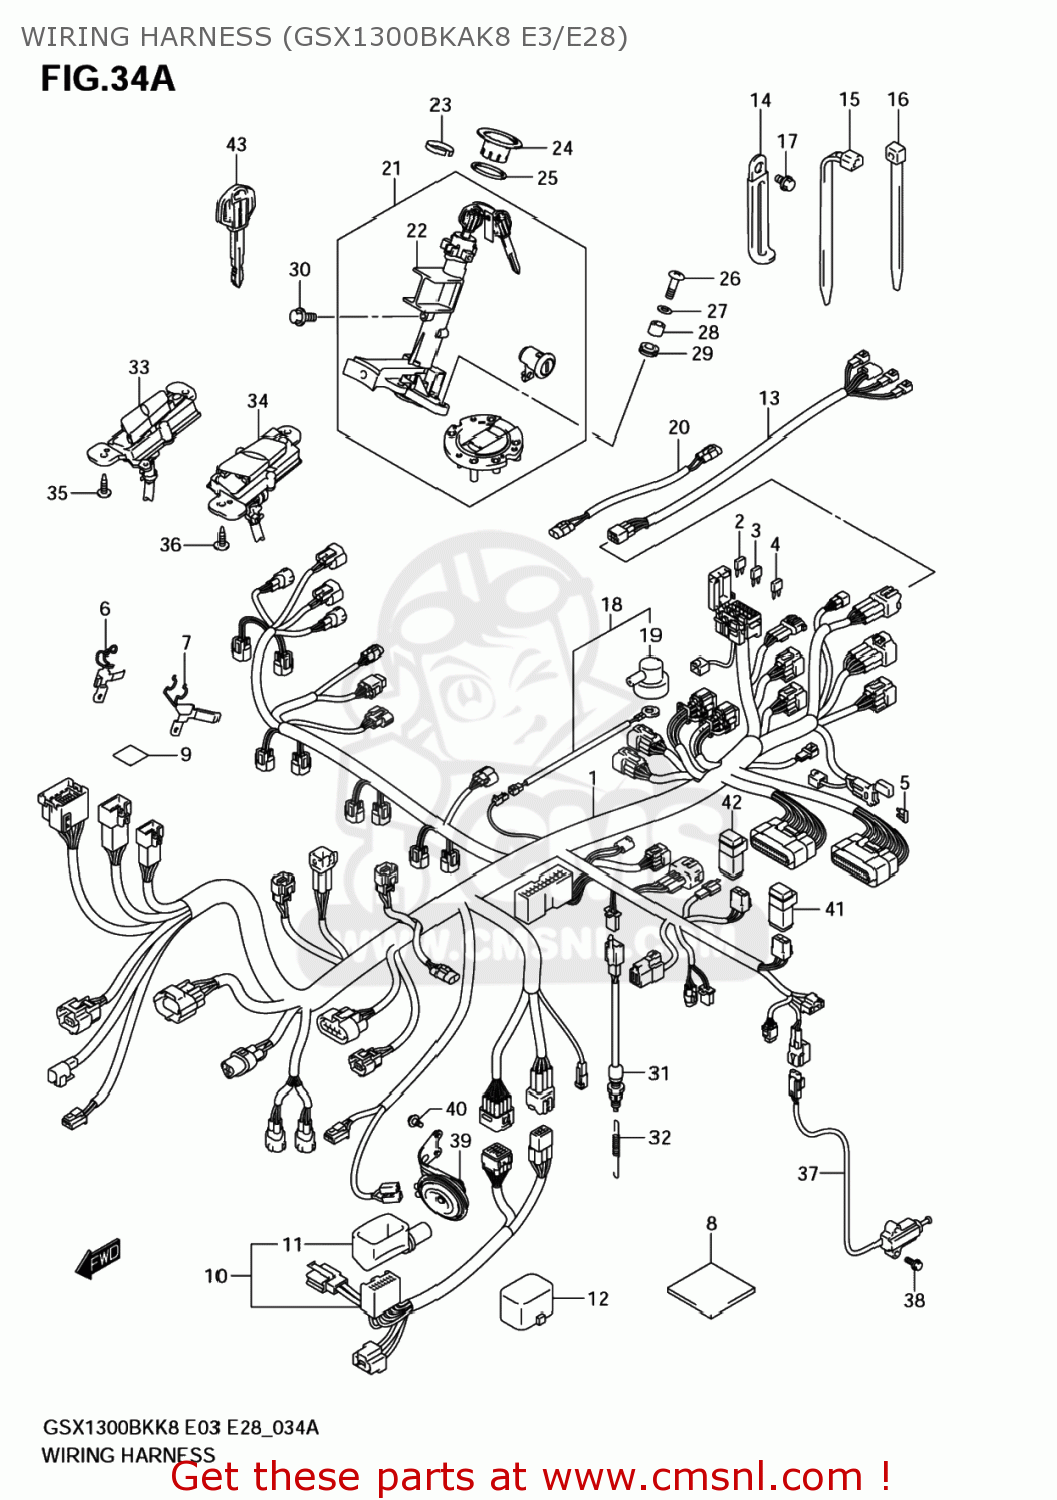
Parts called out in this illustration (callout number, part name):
1	HARNESS,WIRING
2	FUSE(10A)
3	FUSE(15A)
4	FUSE(25A)
5	FUSE(40A)
6	GUIDE,WIRING HARNESS,R
7	GUIDE,WIRING HARNESS,L
8	PROTECTOR(80X80X2)
9	PROTECTOR,20X2
10	HARNESS,WIRING NO.2
11	COVER,CONNECTOR
12	CAP,TS
13	WIRE,RR COMB
14	CLAMP(L:45)
15	CLAMP(L:95)
16	CLAMP(L:145)
17	BOLT
18	WIRE,OIL PRESSURE SWITCH LEAD
19	CAP,OIL PRESSURE SWITCH
20	WIRE,WT SNSR LEAD
21	LOCK SET
22	LOCK ASSY,STEERING
23	PROTECTOR,STEERING LOCK COVER
24	COVER,STEERING LOCK
25	CUSHION,STEERING LOCK COVER
26	SCREW(8X40)
27	WASHER(8.5X18X1.6)
28	SPACER(8.5X12X12)
29	CUSHION
30	BOLT
31	SWITCH ASSY,STOP LAMP
32	SPRING
33	SWITCH ASSY,CONTROLLER,R
34	SWITCH ASSY,CONTROLLER,L
35	SCREW
36	SCREW
37	SWITCH ASSY,SIDE STAND
38	BOLT
39	HORN ASSY
40	SCREW(6X16)
41	RELAY ASSY
42	RELAY ASSY
43	KEY,BLANK
